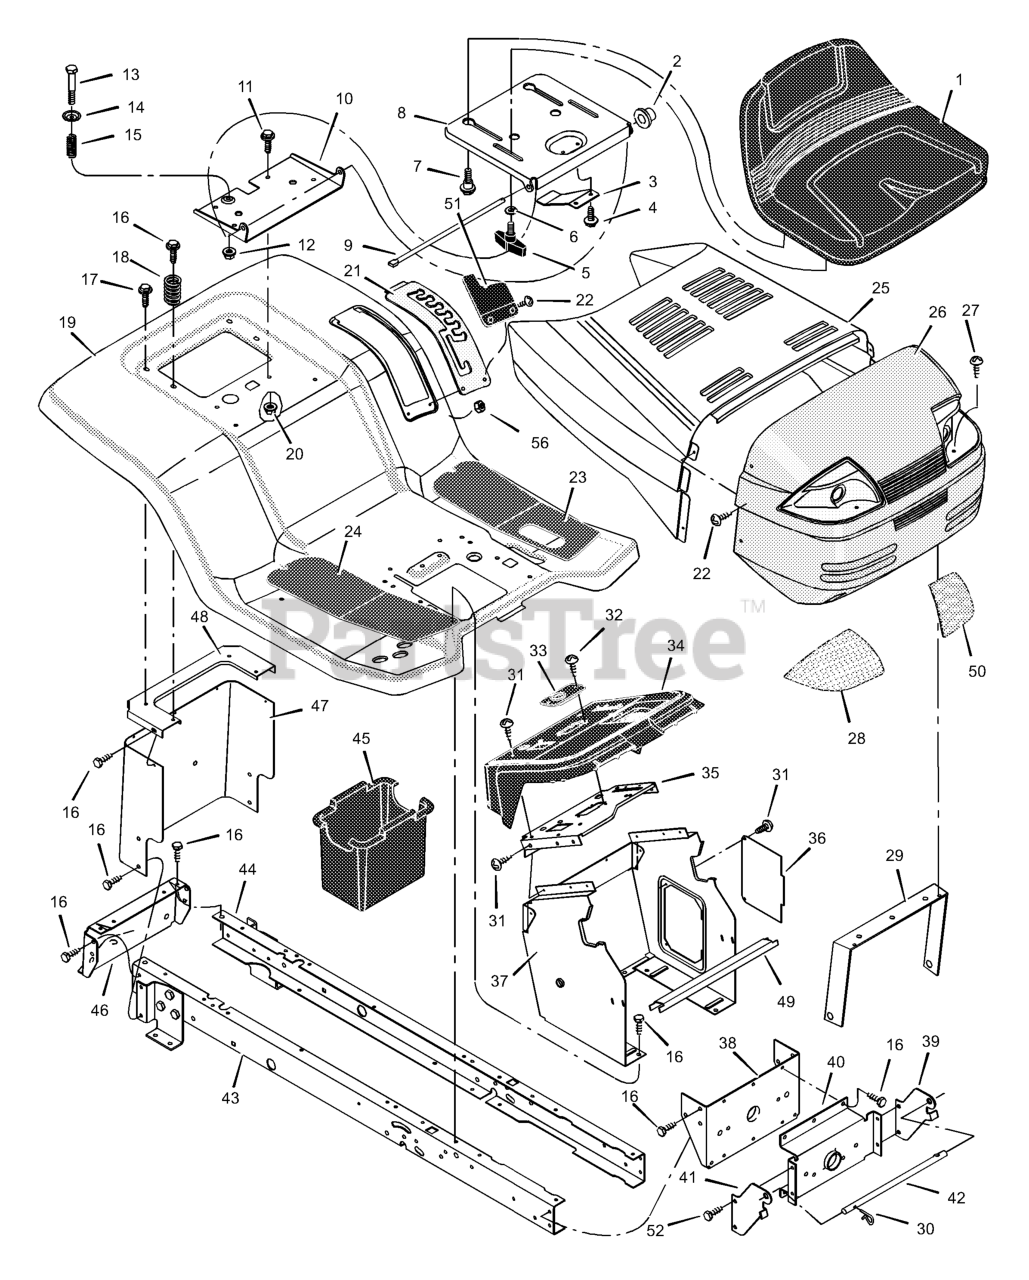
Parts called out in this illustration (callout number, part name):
1	Seat
2	Cap, Push On
5	Bolt, Wing
6	Washer
7	Bolt, Shoulder
8	Support, Seat
9	Rod, Pivot
10	Bracket, Pivot
11	Bolt
13	Bolt, Shoulder
15	Spring
19	Deck, Seat
20	Nut
21	Plate, Index
23	Mat, Left
24	Mat, Right
25	Hood
26	Grille Assembly
27	Screw
28	Lens, Right
29	Brace, Grille
30	Pin, Hair
31	Screw
33	Bearing, Steering
35	Plate, Dash
36	Panel, Access
37	Support, Dash
38	Bracket, Rear Hanger
39	Support, Left Grille
40	Axle, Hanger
41	Support, Right Grille
42	Rod, Pivot
43	Frame, Right
44	Frame, Left
45	Container, Battery
46	Plate, Hitch
47	Plate, Rear
48	Top, Rear Plate
50	Lens, Left
51	Cover, Detent
56	Locknut
